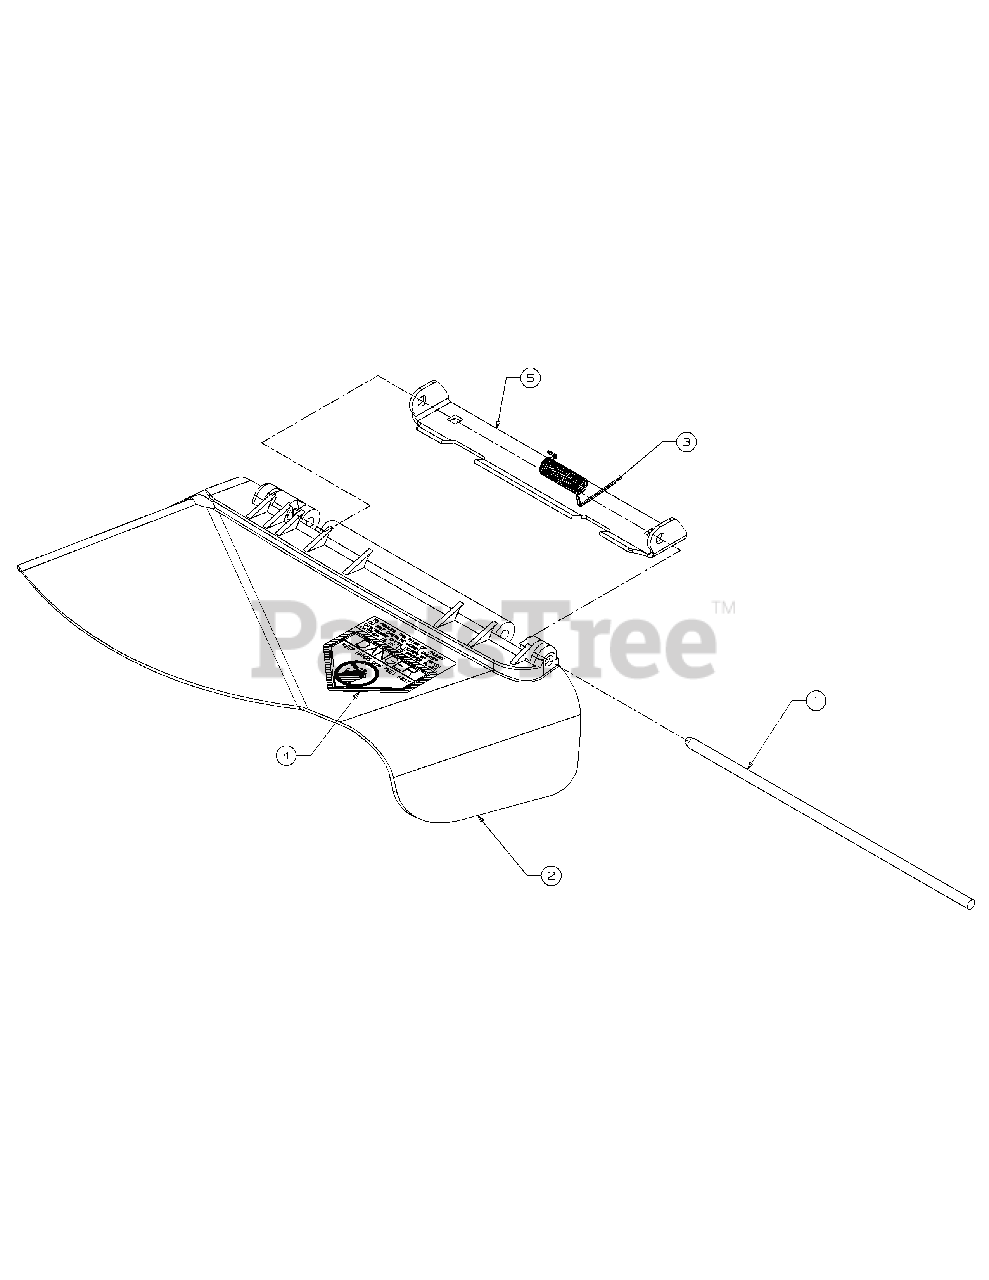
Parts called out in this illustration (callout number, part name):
1	Pin, Hinge, .375 Dia x 14.06
2	Deflector, Chute
3	Spring, Torsion
4	Graphic, Danger
5	Bracket, Mounting
